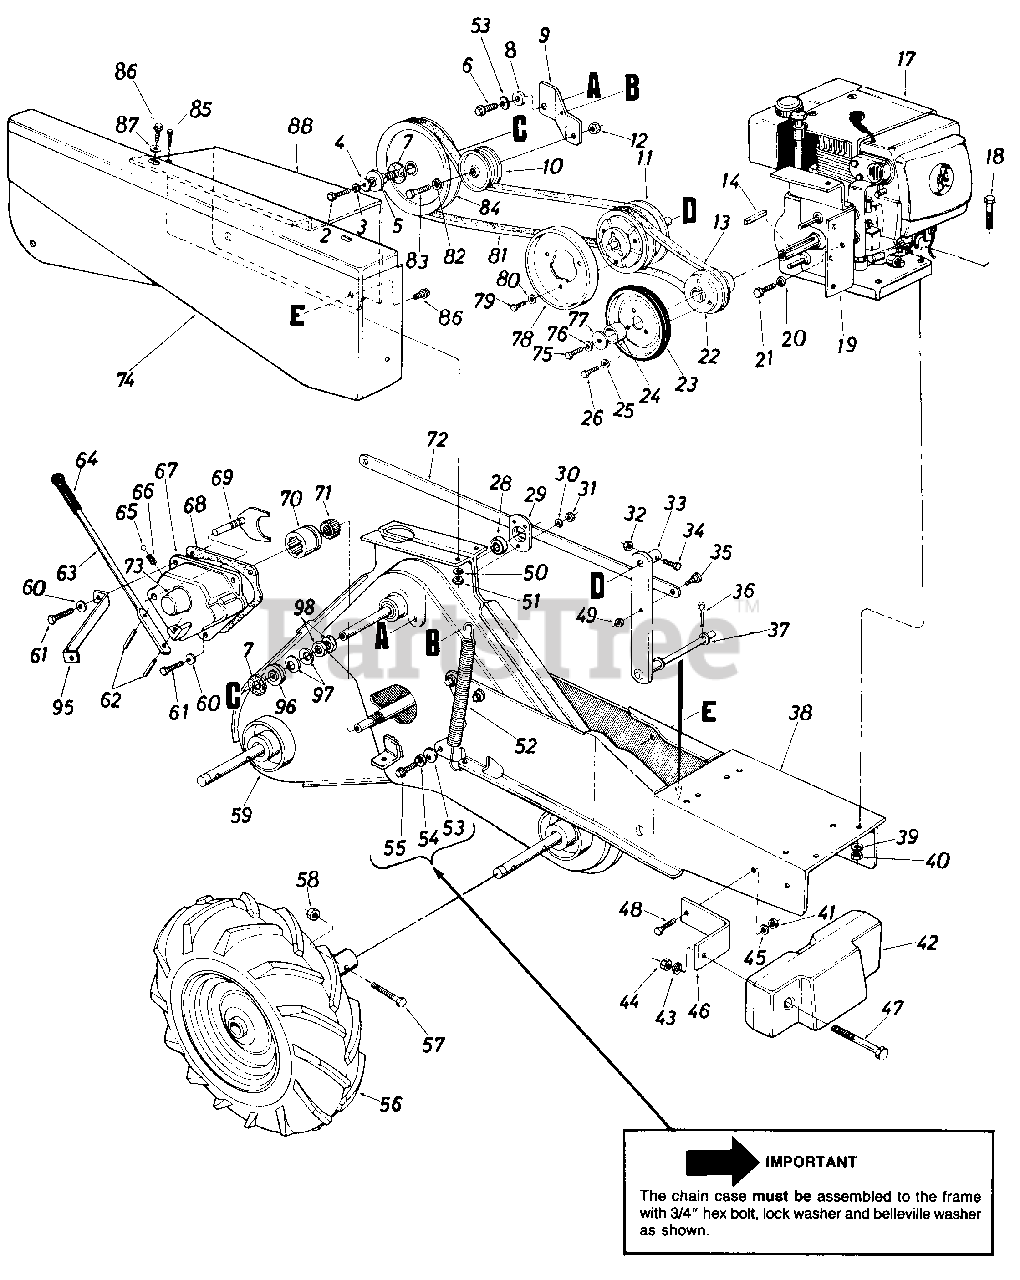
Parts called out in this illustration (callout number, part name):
2	Hex L-Bolt 5/16-24 x 15" Lg
3	L-Wash. 5/16" I.D.*
4	Fl-Wash. 5/16" I.D. x 1.125" O.D.
5	Friction Disc Ass'y.
6	Hex Bolt 3/8-24 x 1.25" Lg.
7	Friction Pad
8	Shoulder Spacer
9	Idler Bracket
10	Fl-ldler 2.75" Dia.
11	Variable Speed Ass'y.
12	Hex Ins. L-Nut 3/8-16 Thd.
13	"V"-Belt 5/8" x 27.0" Lg.
14	Sq. Key 1/4" X 2.00" Lg.*
17	Engine
18	Hex Bolt 5/16-18 x 1.75" Lg.*
19	Belt Cover Support Ass'y.
20	Internal L-Wash. 1/2" I.D.
21	Hex Bolt 1/2-20 x .75" Lg.
22	Engine Pulley Ass'y.
23	Friction Wheel Ass'y.
25	L-Wash. 5/16" I.D.*
26	Hex Bolt 5/16-18 x .50" Lg.*
28	Ball Bearing
29	Bearing Housing 1-3/8" O.D.
30	L-Wash. 1/4" I.D.*
31	Hex Nut 1/4-28 Thd.*
32	Hex Ins. L-Nut 1/4-20 Thd.
33	Variable Speed Brkt. Ass'y.*
34	Hex Bolt 1/4-20 x 1.25" Lg.
35	Shld. Bolt 1/2" Dia. x .25" Lg.
36	Cotter Pin 1/8" Dia. x 1.0" Lg.*
37	Fl-Wash. .686" I.D. x 1.25" O.D.
38	Frame Ass'y.
39	L-Wash. 5/16" I.D.*
40	Hex Nut 5/16-18 Thd.*
41	Hex Cent. L-Nut 3/8-24 Thd.
43	Fl-Wash. .50" I.D. x 1.0" O.D.
44	Hex Nut 1/2-13 Thd.*
45	L-Wash. 3/8" I.D.*
46	Weight Mtg. Brkt.
47	Hex Bolt 1/2-13 x 4.50" Lg.*
48	Hex Bolt 3/8-24 x 1.00" Lg.*
49	Hex Ins. L-Nut 3/8-16 Thd.
50	L-Wash. 1/4" I.D.*
51	Hex Cent. L-Nut 1/4-28 Thd.
52	Spring Idler Bracket
53	Belleville Wash. 318" I.D.
54	L-Wash. 318" I.D.*
55	Hex Self-Tap Scr. 3/8-16 x .75" Lg.
56	Wheel Ass'y. Comp.-R.H.
57	Hex Bolt 3/8-24 x 1.25" Lg.*
58	Hex Ins. L-Nut 3/8-24 Thd.
59	Chain Case Ass'y. Comp.
60	L-Wash. 5/16" I.D.*
61	Hex Tap Tite Scr. 5/16-18 x .75" Lg.
62	Headed Spiral Pin 3/16 x 13/16" Lg.
63	Engagement Lever
65	Ball Detent .250" Dia.
66	Compression Spring
67	Shift Housing-R.H.
68	Gasket-Shift Housing
69	Shift Yoke Ass'y.-R . H .
70	Clutch Dog
71	Clutch Dog Driver
72	Control Brkt.
73	Bearing (Incl. w/Ref. 76)
74	Shroud Belt Cover
75	Hex Bolt 7/16-20 x 2.25" Lg.
76	L-Wash. 7/16" I.D.
77	Fl-Wash. .44 I.D. x 1.38" O.D.
78	Friction Disc
79	Hex Bolt 1/4-28 x .50" Lg.
80	L-Wash. 1/4" I.D.*
81	"V"-Belt 5/8" x 51" Lg.
82	L-Wash. 3/8" I.D.*
83	Hex Bolt 3/8" x 1.50" Lg.*
84	Input Pulley-Chain Case
85	Hex Bolt 1/4-28 x .62" Lg.
86	Hex Wash. Hd. Self-Tap Scr.
87	Fl-Wash. 1/4" I.D.
88	Belt Cover Shroud
96	Floating Disc
97	Spring Bell-Wash.
98	Hex Jam Nut 1.0-14
